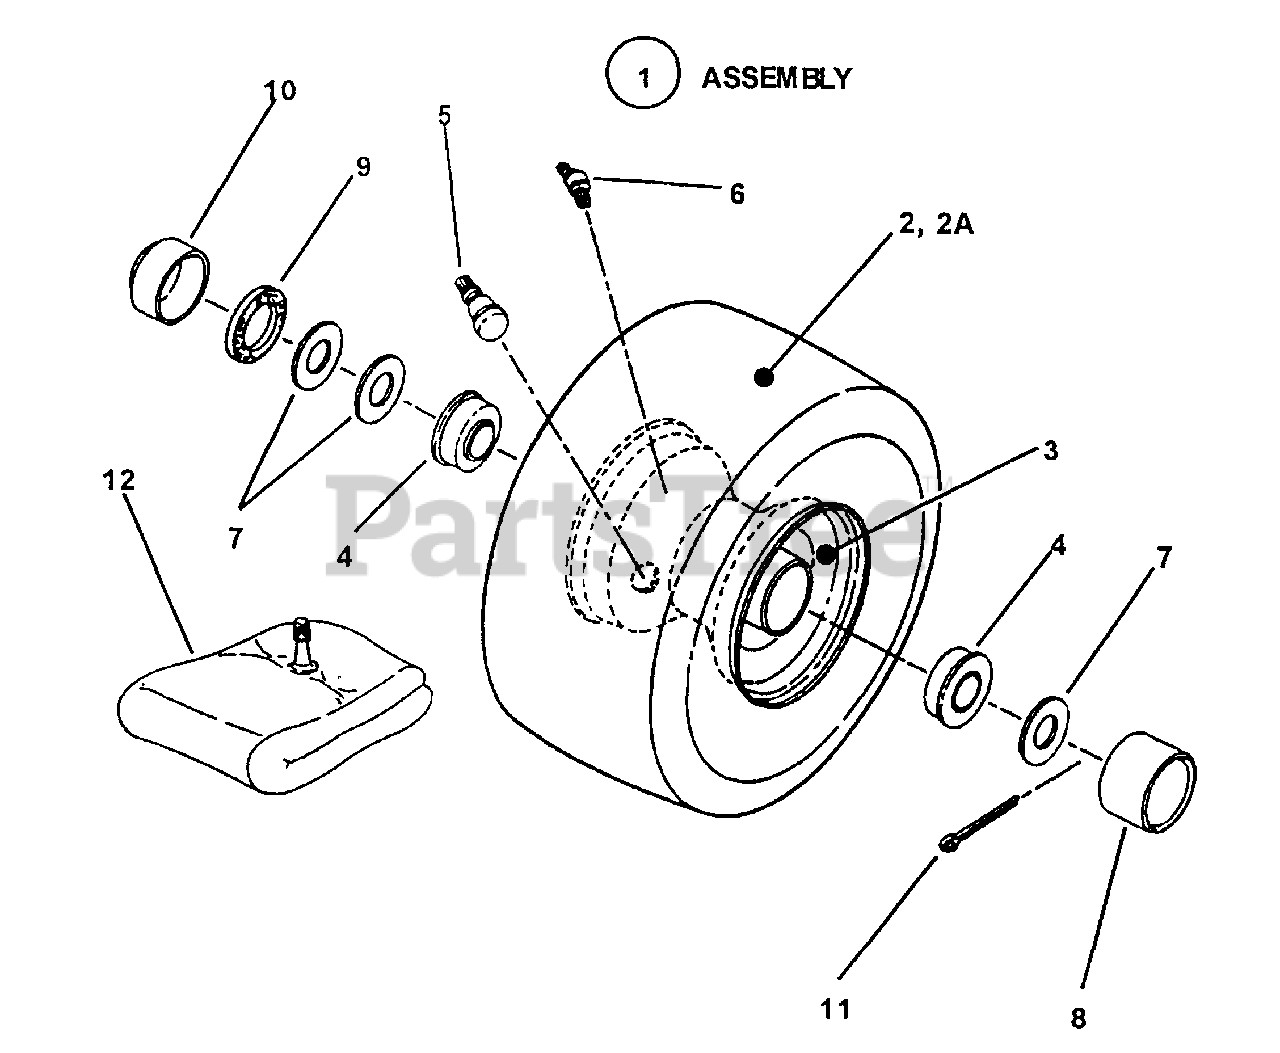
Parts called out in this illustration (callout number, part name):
1	ASSEMBLY, Front Tire & Rim
2	TIRE, 11 x 4.00-4
2A	TIRE, 11 x 4:00-4
3	RIM - Monitor
3	RIM - Carlisle
4	BEARING, Ball 3/4" ID
5	VALVE, Air (Snap-in)
6	FITTING Lube, Straight 3/16"
7	WASHER, 3/4" I.D.
8	CAP, Hub
9	SEAL, Felt
10	CAP, Dust
11	PIN, Cotter 5/32 x 1"
12	TUBE, Inner
